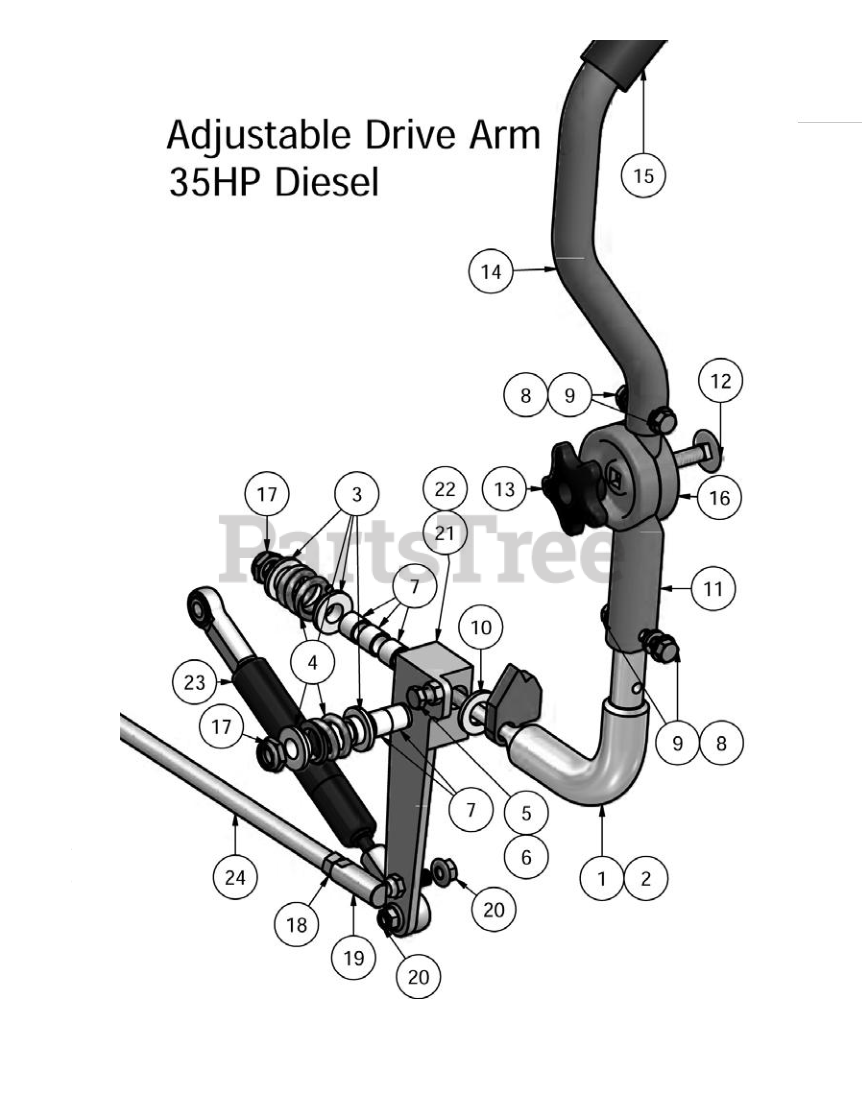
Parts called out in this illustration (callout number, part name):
1	Steering Arm Base-Right
2	Steering Arm Base-Left
3	.515 ID Nylon Shoulder Washer
4	Drive Lever Spring
5	5/16" x 3/4" Hex Bolt
7	.507 ID Nylon Bushing
8	5/16" Lock Washer
9	5/16" x 1/2" Flange Bolt
10	.635 ID Plastic Washer
11	Upper Adjuster for Steering Arm
12	3/8" x 1-1/4" Carriage Bolt
13	Black Knob for Adjustable Steering Arm
14	Upper Steering Arm Tubing-Adjustable
15	Rubber Grip
16	Lower Adjuster for Steering Arm
17	1/2" Nylcock Nut (1/2 Jam)
18	3/8" Fine Threaded Jam Nut
19	3/8-24 Ball joint (female/male)
20	5/16" Flange Nut
21	Drive Arm Lever Housing (Right)
22	Drive Arm Lever Housing (Left)
23	Damper with rod ends
24	Push Rod for 35hp Cat Diesel
